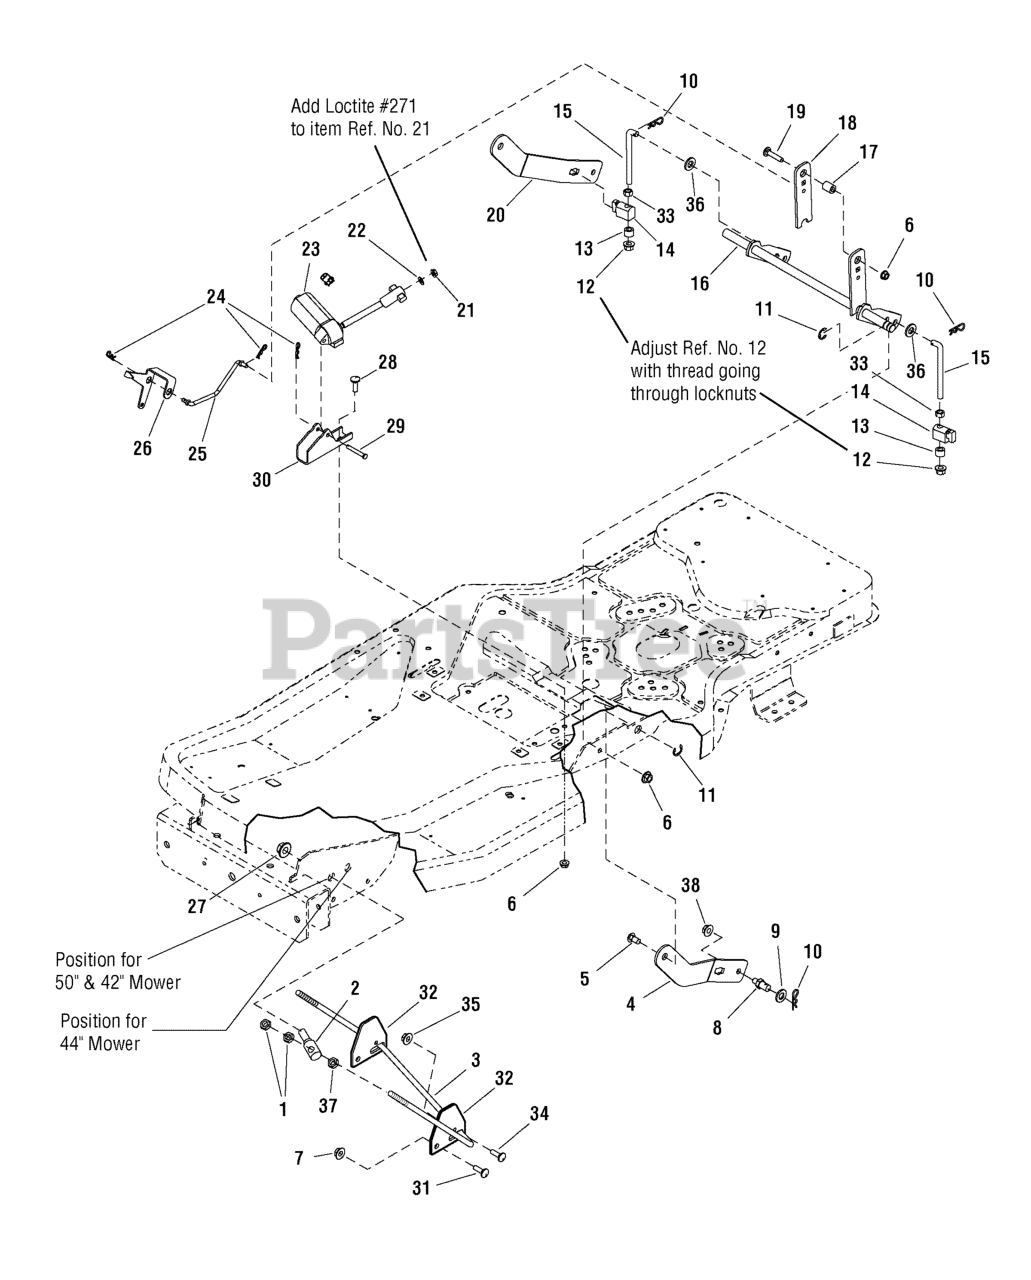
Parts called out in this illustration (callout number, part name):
1	NUT, Hex Jam, 7/16-14, NC-2B
2	TRUNNION
3	ROD, Bail
4	ARM, Mower Lift L.H.
5	BOLT, Shoulder
6	NUT, Hex Whiz Lock Flange, 5/16-18
7	NUT, Hex Whiz Lock Flange, 3/8-16
8	PIN, Threaded Shoulder
9	WASHER, 1/2"
10	CLIP, Hair Pin
11	RING, Klipring, 5/8"
12	NUT, Hex Flange, 3/8-16 ESNA
14	TRUNNION
15	ROD, Mower Lift 3/8-16 x 1 LG Thread
16	LIFT SHAFT ASSEMBLY
17	SPACER, Powdered Metal
18	ARM, Lift Trunnion
19	CARRIAGE BOLT, 5/16-18 x 1-1/2, G5
20	ARM, Mower Lift R.H.
21	NUT, Hex, 1/4-20 L.H. Thread
22	WASHER, 1/4"
23	MOTOR, Mini Actuator
24	PIN, Quick
25	ROD, Height of Cut Indicator
26	INDICATOR, Height of Cut
27	NUT, Hex Flange, Two-Way Lock, 1/2-13
28	BOLT, Carriage, Short Neck, 5/16-18 x 1
29	PIN, Shear
30	BRACKET, Electric Motor Mount
31	CARRIAGE BOLT, 3/8-16 x 3/4, G5
32	PLATE, Pivot Lock
33	NUT, Hex 3/8 - 16
34	CARRIAGE BOLT, 1/4 - 20 x 3/4
35	NUT, Hex Flange Whiz Lock, 1/4 - 20
36	WASHER, 3/8
37	NUT, Hex, 7/16 - 14
38	NUT, Hex Two-Way Lock Flange, 3/8 - 16
